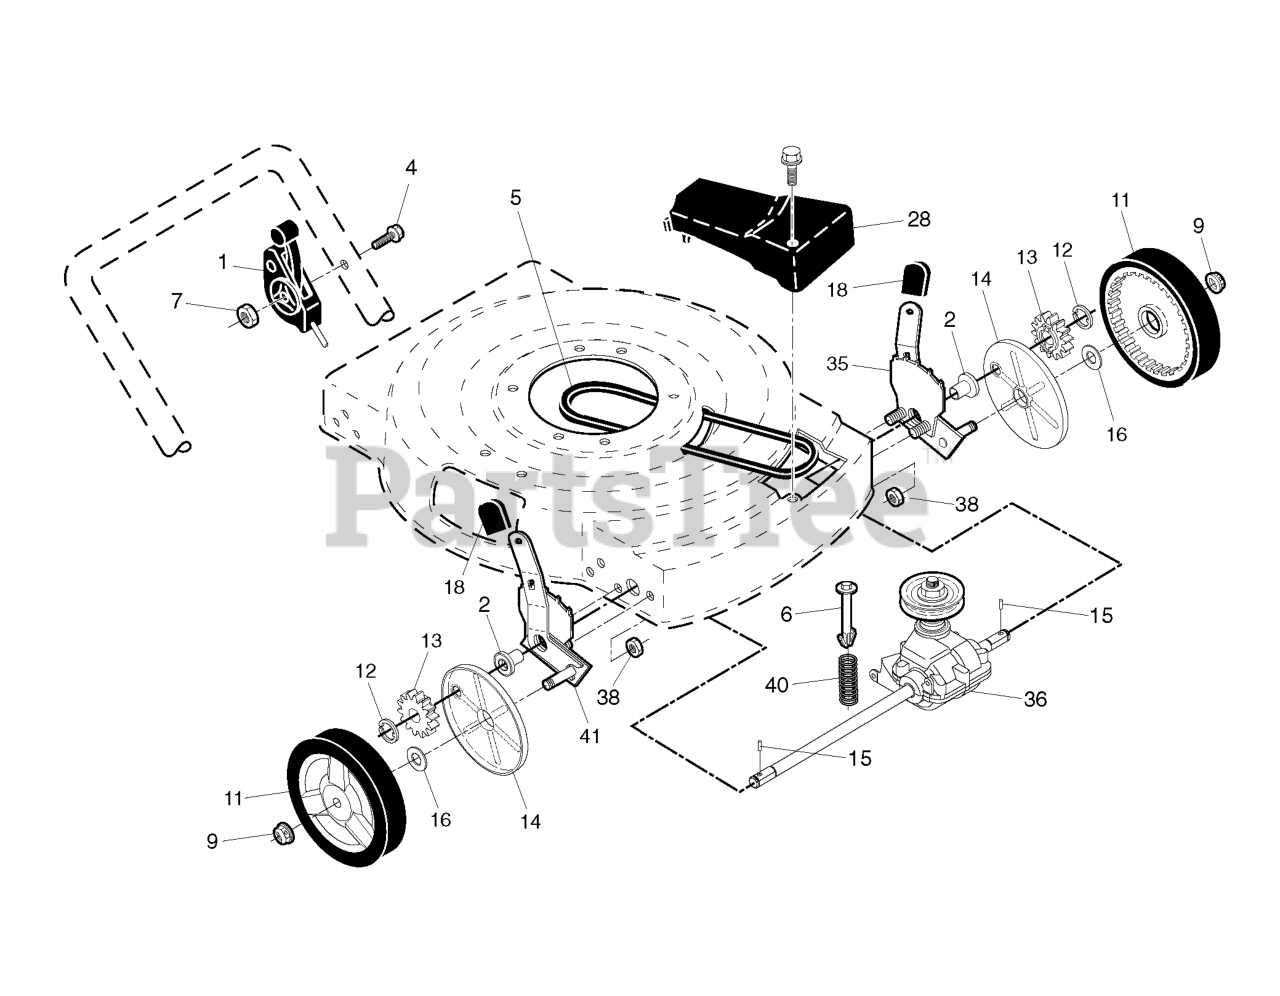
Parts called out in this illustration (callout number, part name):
1	DRIVE CONTROL 59.8 FWGD
2	BEARING.ASM.
4	SCREW.PAN.HEAD
5	BELT THERM .32
6	SPRING RETAINER
7	NUT.HEX.FLANGE.1/4
9	NUT.HEX.FLANGE.3/8-16.LO(3 2)
11	WHEEL.8X1.75.H3SPK.RAD3.GY.BU3
12	E-RING 7/16 RE
13	PINION.14.TEETH.FGD
14	COVER.DUST.WHEEL
15	PAWL, DRIVE
16	WASHER FLUT
18	SELECTOR KNOB
35	KIT ADJUSTER ASM.438151.
36	TRANSMISSION.22.FGD/W/PULLEY
38	LOCKNUT.NYLOC.1/4-20
40	SPRING.EXTENSION
41	KIT ADJUSTER ASM.438148
